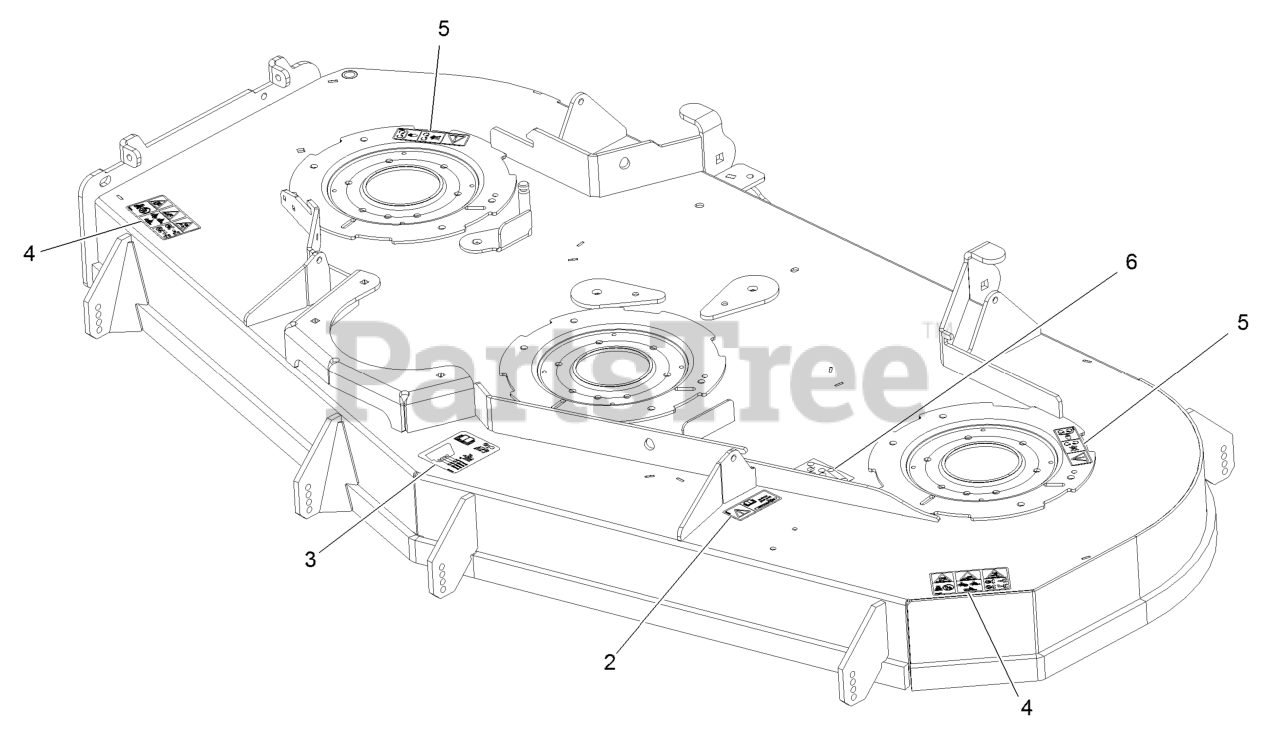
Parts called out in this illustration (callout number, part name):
2	Decal-Bolt Torque
3	Decal-Roller, Anti-Scalp
4	Decal-Danger Thrown Objects
5	Decal-Cover, Missing
6	Decal-Belt Routing
